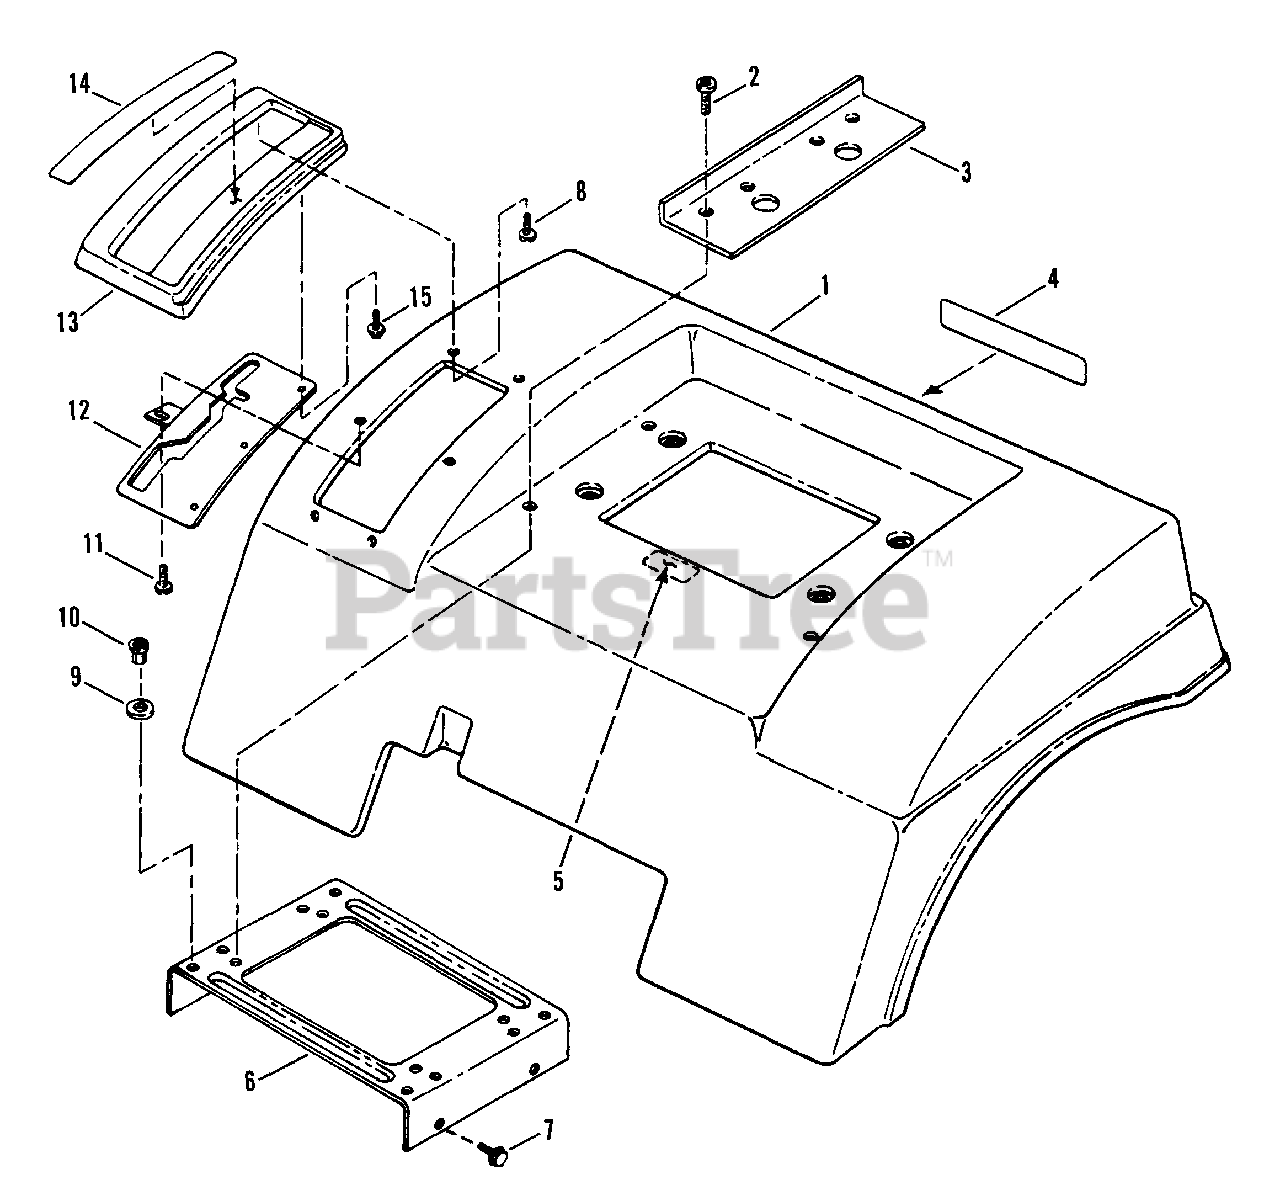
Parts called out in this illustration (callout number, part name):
1	PAN, Seat, Fender
2	SCREW, 5/16-18 x 7/8" Truss Head (Torx)
3	BRACE, Fender
4	LOGO - SNAPPER, Molded (Chrome)
5	DECAL - CAUTION, Battery Installation
6	SUPPORT, Fender (No longer available)
7	SCREW, 5/16-18 x 5/8" Self-Tapping
8	SCREW, #10-24 x 5/8" Self-Tapping
9	WASHER, SAE 7/16
10	RIV-NUT, 5/16-18 (No longer available, try using 7023193)
11	SCREW, #10-16 x 3/4" Self-Tapping
12	DETENT, Gear Shift
13	COVER, Shift
14	DECAL, Shift Cover (Hydro)(No longer available, try using 7073424)
15	SCREW, #10-16 x 1/2" Self-Tapping
